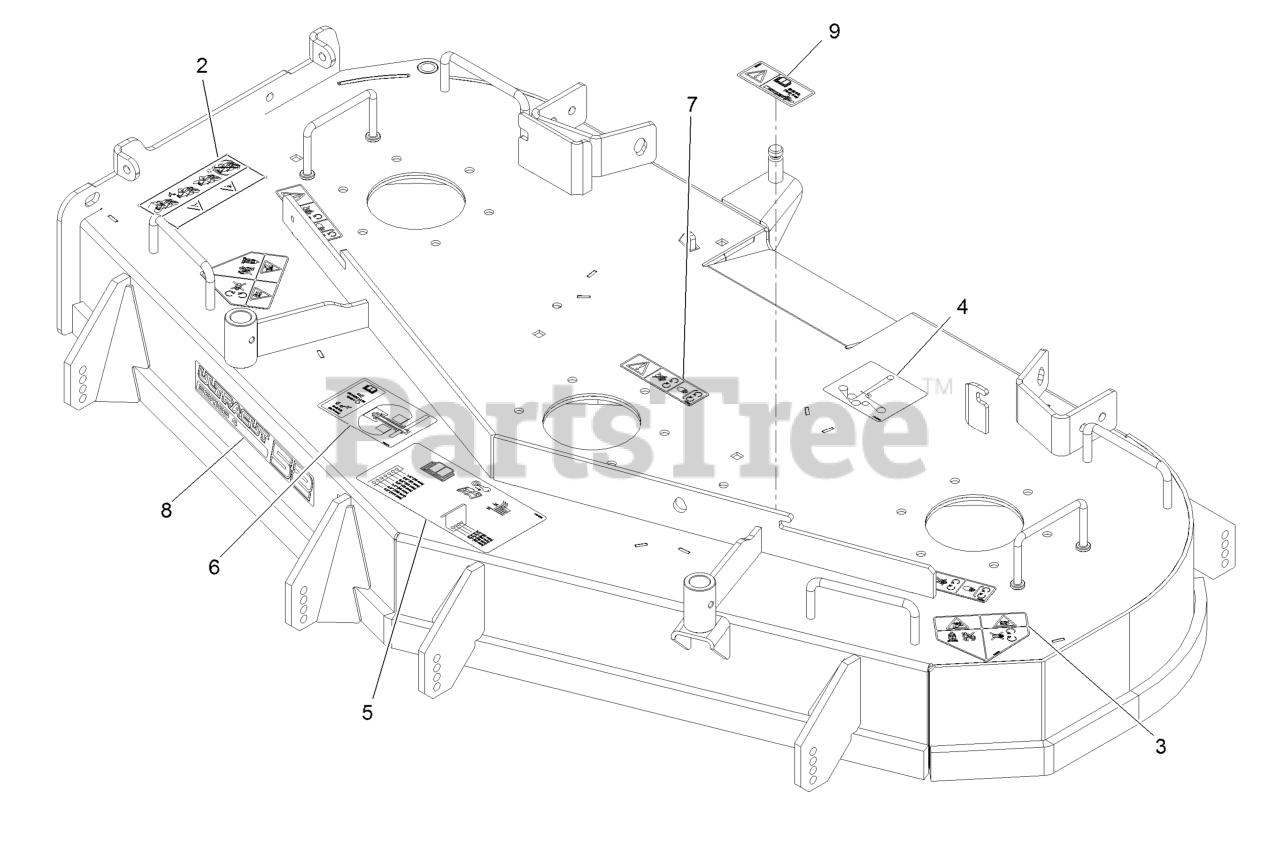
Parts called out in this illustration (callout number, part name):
2	Decal-Warning, Bagger
3	Decal-Danger
4	Decal-Belt Routing
5	Decal-Anti-Scalp
6	Decal-Roller Mounting
7	Decal-Missing, Cover
8	Decal, 524
9	Decal-Bolt Torque
